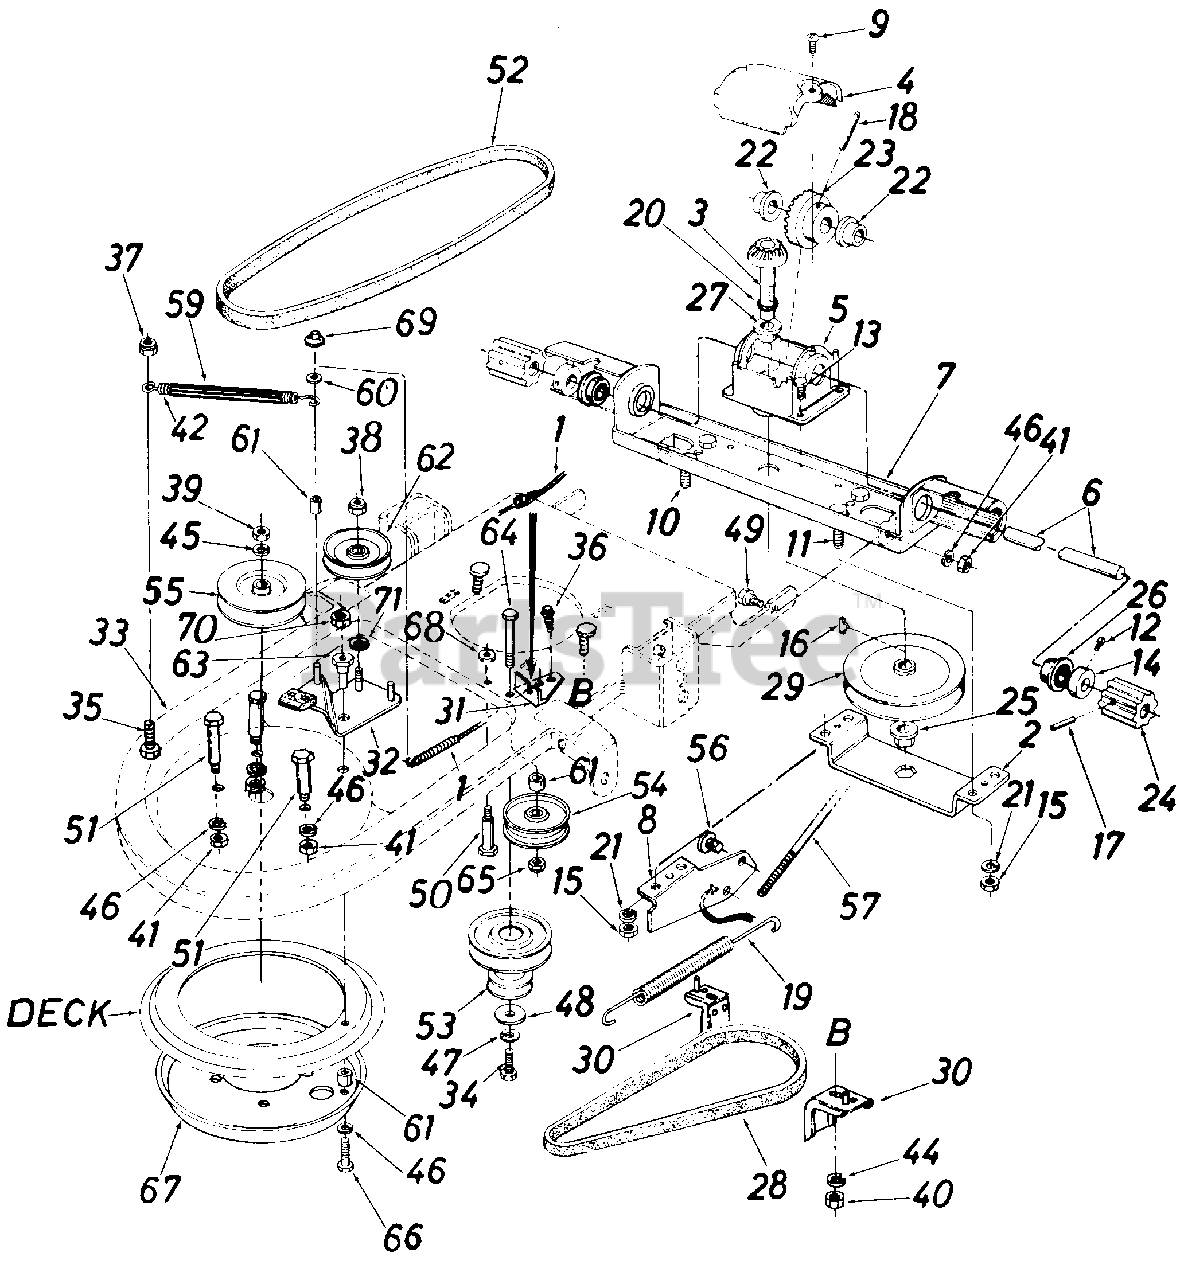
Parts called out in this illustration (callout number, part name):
1	Clutch Cable-39.0"
2	Bottom Frame
3	Pinion Ass'y.
4	Gear Box Cover
5	Gear Box
6	Drive Shaft
7	Top Drive Frame Ass'y.
8	Spring Brkt.
9	Hex Wash. Hd. F-Tap Scr. #8-32 x .38" Lg.
10	Hex Bolt 1/4-20 x .88" Lg.
11	Hex Bolt 1/4-20 x .75" Lg.
12	Set Scr. 5/16-18 x .25" Lg.
13	Hex Wash. Hd. AB-Tap Scr. 1/4" x .62" Lg.
14	Collar 5/8" I.D.
15	Hex Nut 1/4-20 Thd.
16	#2 Woodruff Key 31/32" x 1/2" Dia
17	Spring Pin .188" Dia. x 1.12" Lg.
18	Spring Pin Spiral .188" Dia. x 1.25" Lg.
19	Extension Spring
20	O-Ring
21	L-Wash. 1/4" I.D.
22	Flange Bearing .630" I.D.
23	Bevel Gear
24	Drive Pinion
25	Hex Flange Bearing .503" 1. D.
26	Ball Bearing.630" I.D.
27	Hex Flange Bearing .503" I. D. w/Groove
28	V-Belt 1/2" x 33.0" Lg.
29	1/2" V-Pu l ley .504" I.D. x 6.5" O.D.
30	Belt Keeper Ass'y.
31	Clutch Cable Brkt.
32	Idler Brake Brkt. Ass'y.
35	Hex Bolt 1/4-20 x .75" Lg.
36	Hex Wash. Hd. AB-Tap Scr. 1/4" x .62" Lg.
37	Hex Cent. L-Nut 1/4-20 Thd.
38	Hex Ins. L-Nut 3/8-24 Thd.
39	Hex Jam Nut 5/8-11 Thd.
40	Hex Nut 5/16-18 Thd.
41	Hex Nut 3/8-16 Thd.
42	Extension Spring
44	L-Wash. 5/16" I.D.*
45	L-Wash. 5/8" I.D.
46	L-Wash. 3/8" I.D.
47	L-Wash. 3/8" I.D.-H.D.
48	Fl-Wash. .406" I.D. x 1.25"O.D.
49	Shld. Bolt .498" Dia. x .340"
50	Shld. Bolt .498" Dia. x 1.64"
51	Shld. Bolt .498" Dia. x 1.450"
52	V-Belt 1/2" x 44.0" Lg.
53	Two Step Engine Pulley
54	Flat Idler Pulley
55	1/2" V-Pulley .503" I.D. x 4.50" O.D.
56	Adj. Ferrule
57	Drive Control Rod
59	Plastic Tube
60	Fl-Wash. .343 I.D. x .687 O.D. x .063
61	Spacer .376 I.D. x .622 O.D. x .44" Lg.
62	4.0" Idler Pulley
63	Shoulder Spacer
64	Hex Bolt 3/8-24 x 1.75" Lg.
65	Hex L-Nut 3/8-24 Thd.
66	Hex Bolt 3/8-24 x 1.5" Lg.
67	Blade Reinforcement Plate
68	Hex L-Nut 3/8-16 Thd.
69	Push Cap 1/4"
70	Hex Jamut 3/8-24 Thd .
71	Fl-Wash. .406 I.D. x 1.25 O.D. x .172 Thk.
